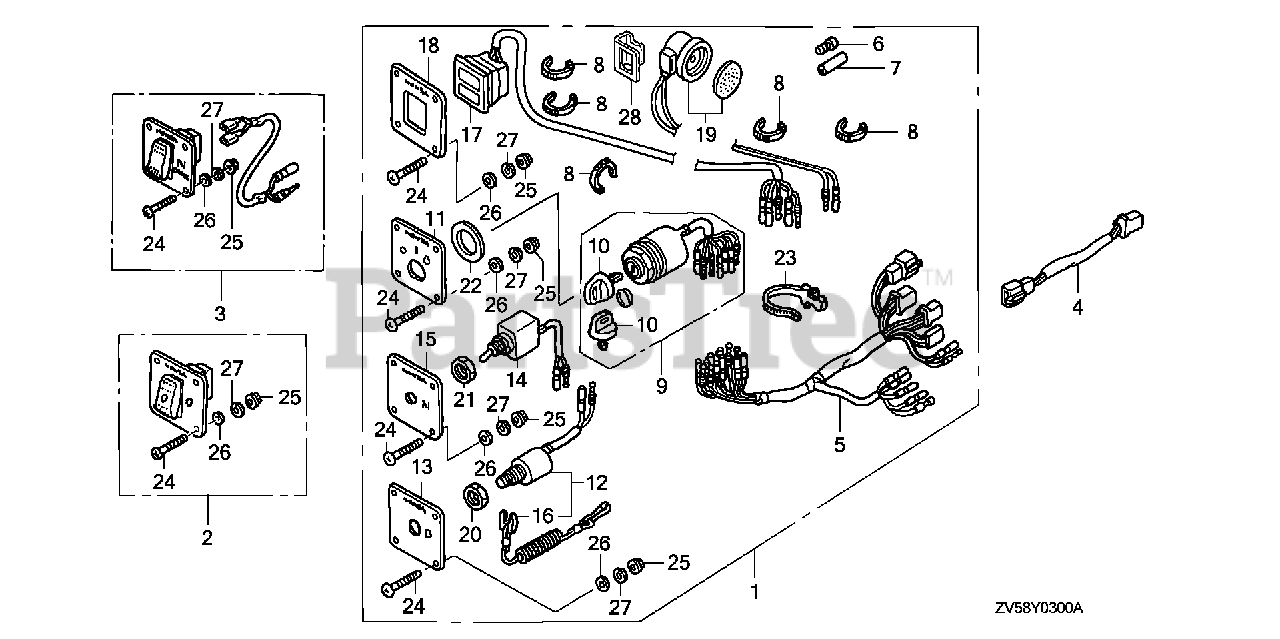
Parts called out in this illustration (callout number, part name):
1	PANEL KIT, CONTROL (B)
1	PANEL KIT, CONTROL (2-LED) (A) (NOT AVAILABLE)
4	SUB-HARNESS ASSY., POWER TRIM-TILT (A)
5	HARNESS ASSY., SWITCH PANEL
6	PLUG, CONNECTOR (INNER) (TROLLING CONTROL)
7	PLUG, CONNECTOR (OUTER) (ENGINE NO.)
8	TIE, CABLE (NATURAL 2.4X92) Use up to Frame SN 1300359.
9	SWITCH ASSY., COMBINATION DUAL QTY = (2) (SINGLE)
10	KEY ASSY., COMBINATION SWITCH (35100-ZV5-003 ONLY) DUAL QTY = (4) (SINGLE)
11	PANEL, SWITCH
12	SWITCH ASSY., EMERGENCY STOP
13	PANEL, EMERGENCY STOP SWITCH
14	SWITCH ASSY., SOLENOID
15	PANEL, SOLENOID
16	WIRE, EMERGENCY (SINGLE) (DUAL)
17	LAMP ASSY., INDICATOR (2-LED)
18	PANEL, INDICATOR
19	BUZZER, WARNING
20	NUT, HEX. (16MM) DUAL QTY = (2) (SINGLE)
21	NUT, HEX. (12MM)
22	WASHER, PLAIN
23	BAND, WIRE HARNESS (150MM) (NATURAL) DUAL QTY = (2) (SINGLE)
24	SCREW, PAN (5X40)
25	NUT, FLANGE (5MM)
26	WASHER, PLAIN (5MM)
27	WASHER, SPRING (5MM) DUAL QTY = (8) (SINGLE)
28	BRACKET, BUZZER
